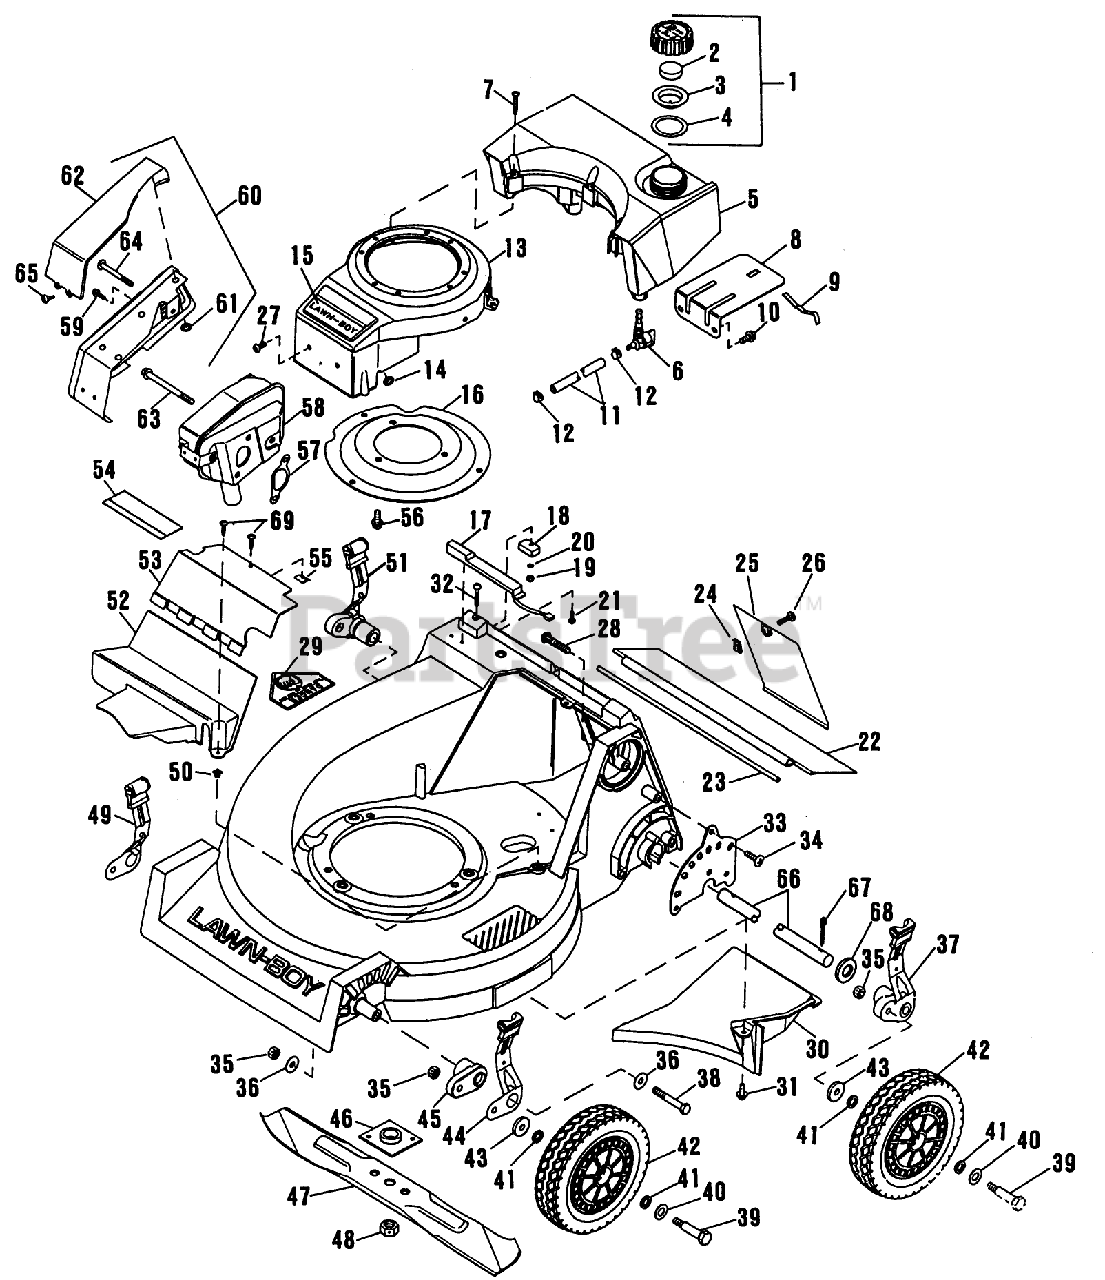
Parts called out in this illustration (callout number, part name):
1	CAP AY - F/OIL SM
2	BAFFLE - FOAM SM
4	GASKET-FUELCAP SM
6	DISC/LB SER.BUL.#6
7	DISC.LB SER.BUL.#6
8	DISC. LB SER.BUL.#6
9	SPRING
11	GAS LINE SM
12	HOSE CLAMP SM
14	NUT-PUSH
17	SWITCH AY DELTA
24	SPEED NUT LARSON
25	DOOR-ACCESS ELECT.
26	SCREW-CROSS RECESS
30	CHUTE BAFFLE NYL
33	PLATE HGT CMS
34	SCREW-BHTF
35	NUT-JAM, LOCKING
36	WASHER-PLAIN
40	SPACER
41	WASHER
42	WHEEL&TIRE 8" TRI
43	WASHER
44	KNOB & SPRING CMS
46	PLATE AND COLLAR ASM
48	NUT-BLADE
49	KNOB & SPRING CMS
50	NUT-CLIP
55	NUT-SPEED
57	GASKET - EXH SM
59	SCREW S
60	MUFFLER GUARD AY
61	NUT-PUSH
62	COVER MUFFLER CP
63	SCREW-SEMS
64	SCREW SM
65	SCREW SM
66	ROD HGT ADJ R GLM
68	SPACER
69	SCREW S
